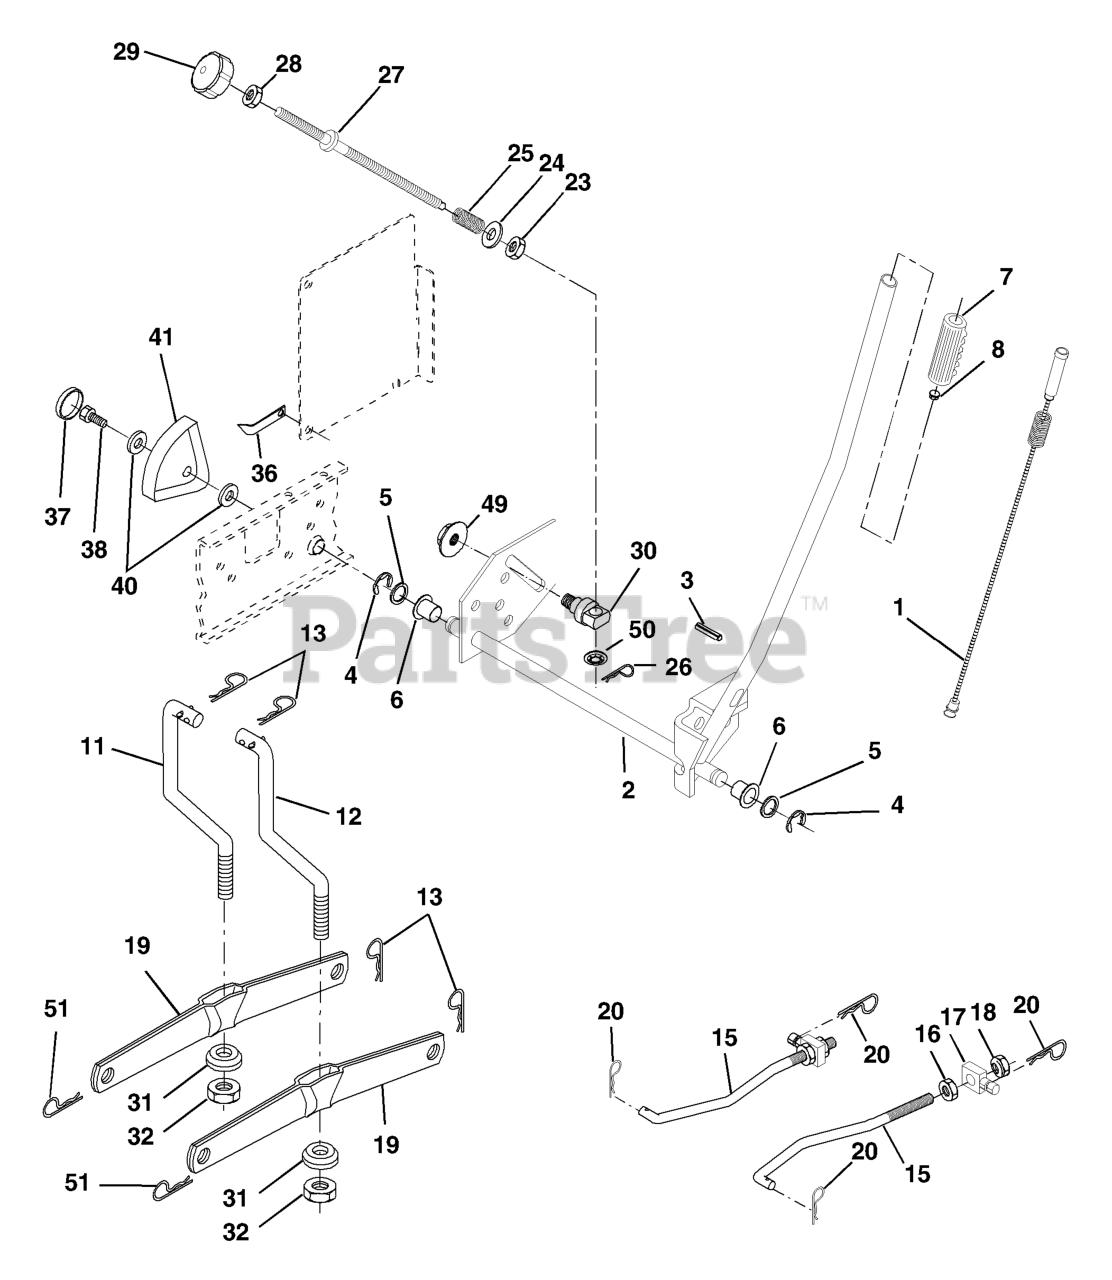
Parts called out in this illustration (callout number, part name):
1	WIRE ASM INNER W/ PLUNGER LT
2	SHAFT ASM R HANDLE
3	PIN GROOVE.
4	RETAINING RING LT
6	BEARING.NYLON
7	GRIP HANDLE
8	PLUNGER BUT KIT
11	LINK
12	LINK
13	RETAINER-SPRNG RB
15	LINK FRONT
16	NUT.HEX.JAM.1/2-13
17	TRUNION
18	NUT.LK.W/WSH.1/2.
19	ARM.REAR.SUSPENSION
20	SPRING RETAINER
25	SPRING**
26	RETAINER CLIP
27	ROD ADJ LIFT
28	NUT
29	KNOB INF 3/8-16
31	BEARING PIVOT
32	NUT CROWNLOCK 3/8-24
36	POINTER, HEIGHT INDICATOR(2 2)
38	SCREW 5/16-18X1
41	HEIGHT INDICATOR
49	NUT
50	NUT PUSH M
51	RETAINER-SPRNG RB
